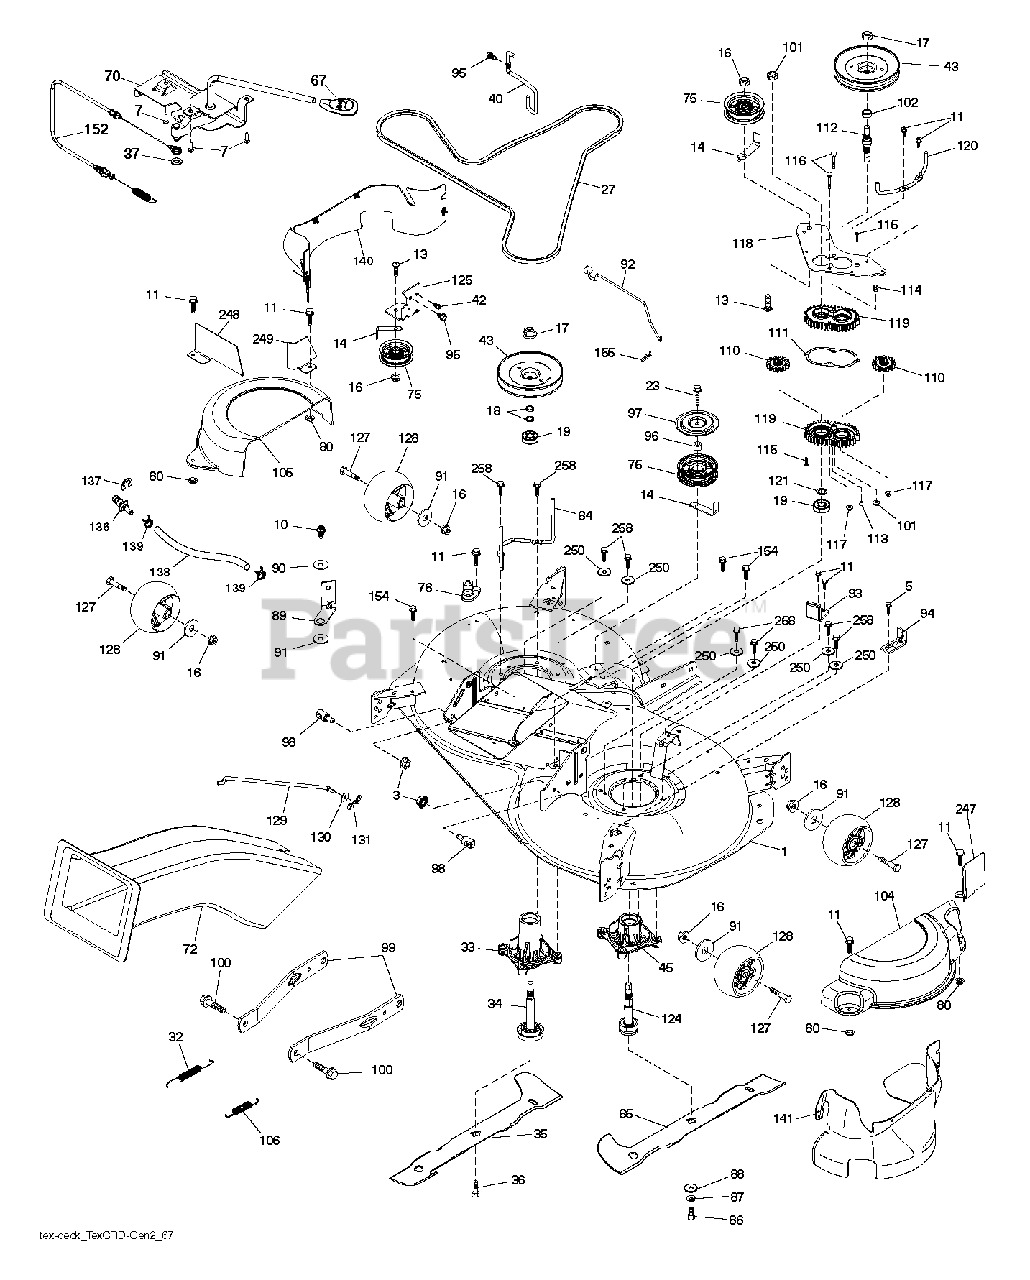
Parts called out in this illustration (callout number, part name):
3	NUT LOCK HEX FLANGE 5/16-18
5	BOLT.5/16HEX.WHS.HD
7	SCREW.#10 X 0.750.BOS THREAD
10	SCREW 3/8-16X1
11	SCREW.1/4-20X5/8
13	BOLT.3/8-16X1.50
14	KEEPER, BELT IDLER
16	NUT LOCK FLG 3/8-16 UNC
17	NUT.FLANGE.LOCK.TOP
18	WASHER.SPACER.MANDREL
23	SCREW LT
32	SPRING RETURN
36	BOLT.WASHER.ASM.7/16-2
40	KEEPER BELT ENGINE LH
42	SCREW
67	HANDLE.CLUTCH.CABLE.LT
70	CLUTCH.ASM.MANUAL.LT.PRED
72	CHUTE 10797 TEX GEN
75	FLAT IDLER PULLEY
80	PALNUT 1/4
87	LOCKWASHER
88	WASHER.BLADE
89	ARM BRAKE MOWER
90	SPACER.RETAINER
94	BRKT.CLUTCH.CABLE
95	SCREW, 3/8-16X3/4
98	STUD.FASTNER.W/ANTI-ROTATE
99	ARM.SUSPENSION.MOWER.R
100	BOLT.SHOULDER
102	SPACER BEARING
106	SPRING.BRAKE.RETURN.38"
117	NUT T
127	BOLT.SHOULDER.3/8-16X3-5/8
128	WHEEL. GUAGE RALLY
130	WASHER
131	PIN.COTTER.5/16.BOW TI
137	RING CLIP
155	RETAINER M
248	GUARD.STEEL.CRD.MANDR
249	GUARD.STEEL.CRD.MANDR
250	WASHER
258	Hex Washer Head Bolt, .313-18 X 1.19
